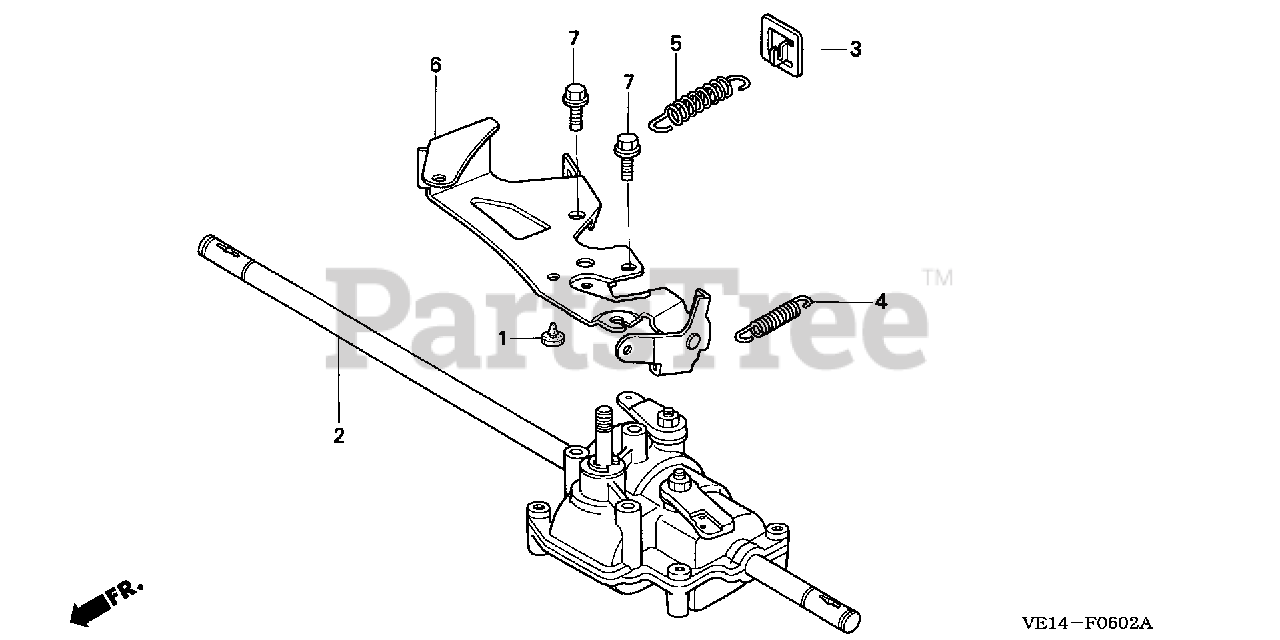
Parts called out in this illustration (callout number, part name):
1	RUBBER, TANK STOPPER
2	TRANSMISSION KIT
3	PLATE, TENSION SPRING
4	SPRING, CLUTCH RETURN
5	SPRING, WHEEL TENSION
6	HOLDER, WIRE
7	BOLT, FLANGE (8X16)
NI	ARM, CLUTCH
NI	ARM, CHANGE
NI	KEY, WOODRUFF
